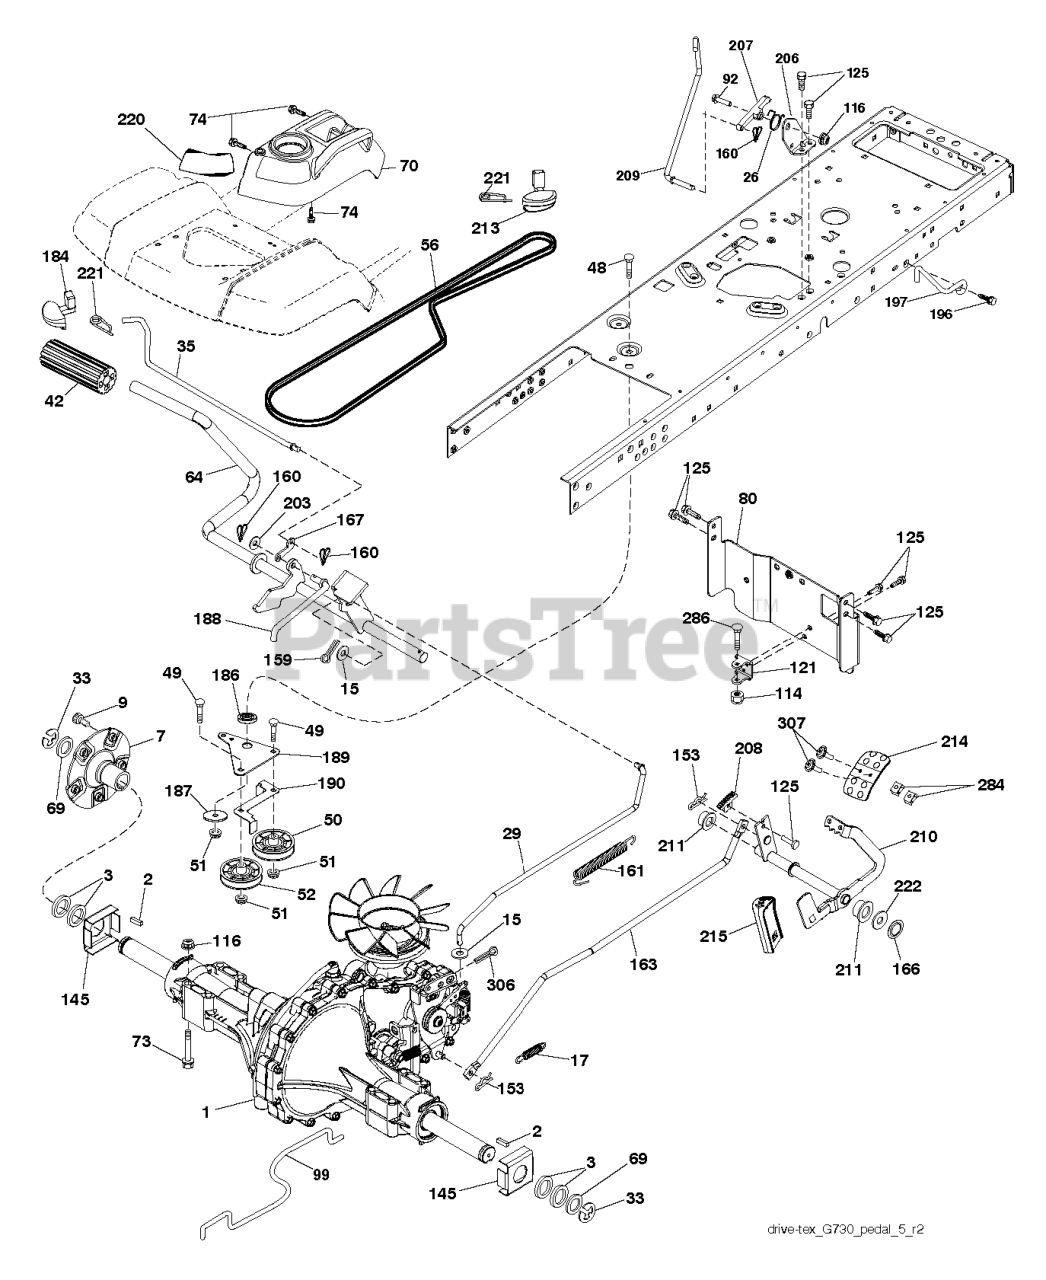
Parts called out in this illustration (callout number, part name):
2	KEY 1/4 X 2.5
7	HUB.ASM.WHEEL.REAR.23"TEX
15	WASHER
17	SPRING.BRAKE.HG3000/3500
26	SPRING.RETURN.CRUISE
33	E RING HYT
35	ROD .BRAKE. PARKING. GT. HUSQ.
42	PEDAL COVER T
48	BOLT.3/8-16X1.50
50	IDLER.FLAT.910.OFFSET
51	NUT LOCK FLG 3/8-16 UNC
52	IDLER.V-GROOVE.910.OFFSET
56	V-BELT.GROUND.DRIVE.
64	SHAFT.ASM.PEDAL.BRK.CNTR
70	RP CONSOLE.ASM.PCH.W/TB
73	BOLT HEX FLGHD 5/16-18X3 GR. 5
74	SCREW.HI-LO.CONSOLE
80	STRAP.TORQUE.YT.G700
92	BOLT
99	SPRING.BYPASS.YT.G700
114	NUT.71038.31-18.HEX.NYLOCK
116	NUT LOCK HEX FLANGE 5/16-18
121	BRACKET STRAP TORQUE
125	SCREW
145	WASHER.AXLE.FLANGE.HG-3000
153	RETAINER M
159	COTTER PIN
160	RETAINER CLIP
161	SPRING, RETURN LT
163	ROD PEDAL CONTROL
166	NUT.PUSH.625
167	LATCH.BRAKE.SPRING
184	HANDLE.PARKG.BRK.HUSQ X667
186	SPACER.RETAINER
187	WASHER 12/32X2X10GA
188	RP.LINK.CLUTCH.GROUND.DRIVE
189	BELLCRANK.GROUND.DRIVE.TRAPPED
190	KEEPER BELLCRANK ROUND DRIVE
196	SCREW 3/8-16X1
197	BRKT.ANIT-ROTATION.CLUTCH
203	WASHER
206	BRKT.MOUNT.LATCH.CRUIS
207	LATCH.CONTROL.CRUISE
208	GEAR.SECTOR.CONTROL.CR
209	ROD.CONTROL.CRUISE.GT.
210	ROCKER.ASM.PEDAL.CONTR
211	BEARING.NYLON
213	KNOB.CONTROL.CRUSIE.HU
214	PEDAL.FORWARD.HUSQVARNA.DEALER
215	PEDAL.REVERSE.TEX.GT.4
220	REFLECTOR.RH.TEX GT
221	RETAINER.SPRING.CLIP.H
222	WASHER 21/32 X 1-1/4 X 10 GA.
284	NUT.U-CHNL.1/4-20.550DP.350PNL
286	BOLT.5/16-18X2.5
306	PIN COTTER
307	SCREW.MACHINE.CR.1/4-20
